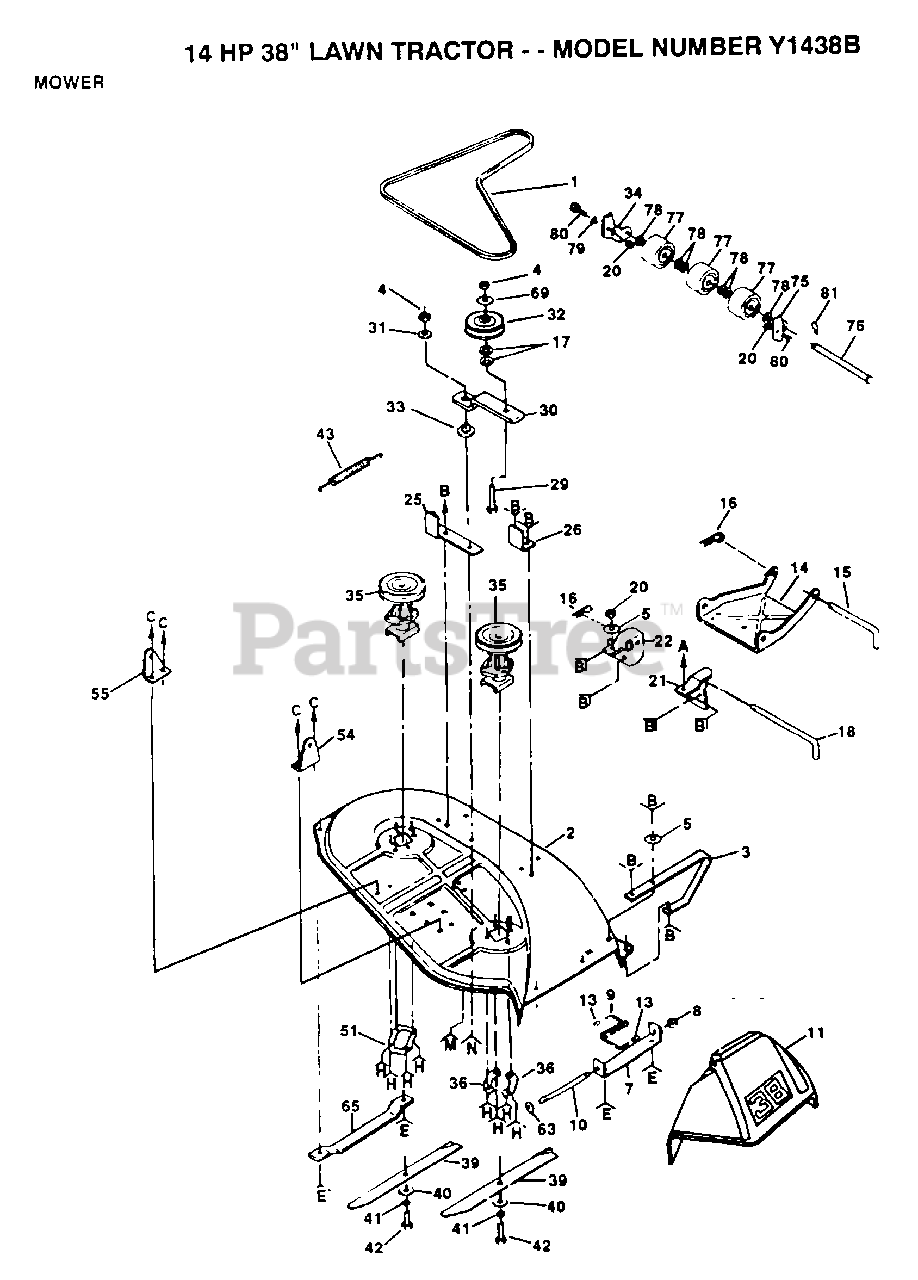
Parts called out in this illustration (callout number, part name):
1	BELT-V.79.1.MWR
5	WASHER M
8	NUT PUSH M
10	ROD-HINGE T
11	DEFLECTOR-SHLD T
13	CAP-SLEEVE LT
14	LINK.PARALLEL
15	"ROD, FRT. PARAL T"
16	SPRING.RETAINER
17	WASHER
18	HINGE PIN T
21	BRACKET RH LT
22	BRACKET LH T
25	SUPPORT ARM T
26	STOP T
29	BOLT
31	SPACER RETAINER
33	"WASHER, WEAR LT"
34	BRACKET LH T
36	SUPPORT PLATE LT
39	"BLADE.38"" HI-LI"
40	WASHER
42	BOLT.3/8-24X1-1/2
43	"SPRING.EXT.8.5"""
51	SUPPORT T
54	"BRKT,SUSP RH T"
55	"BRKT,SUSP REAR LH"
63	WASHER
65	RUNNER-LH M
69	WASHER
75	BRACKET RH T
76	PIVOT PIN T
77	ROLLER T
78	WASHER T
80	BOLT
81	COTTER PIN
